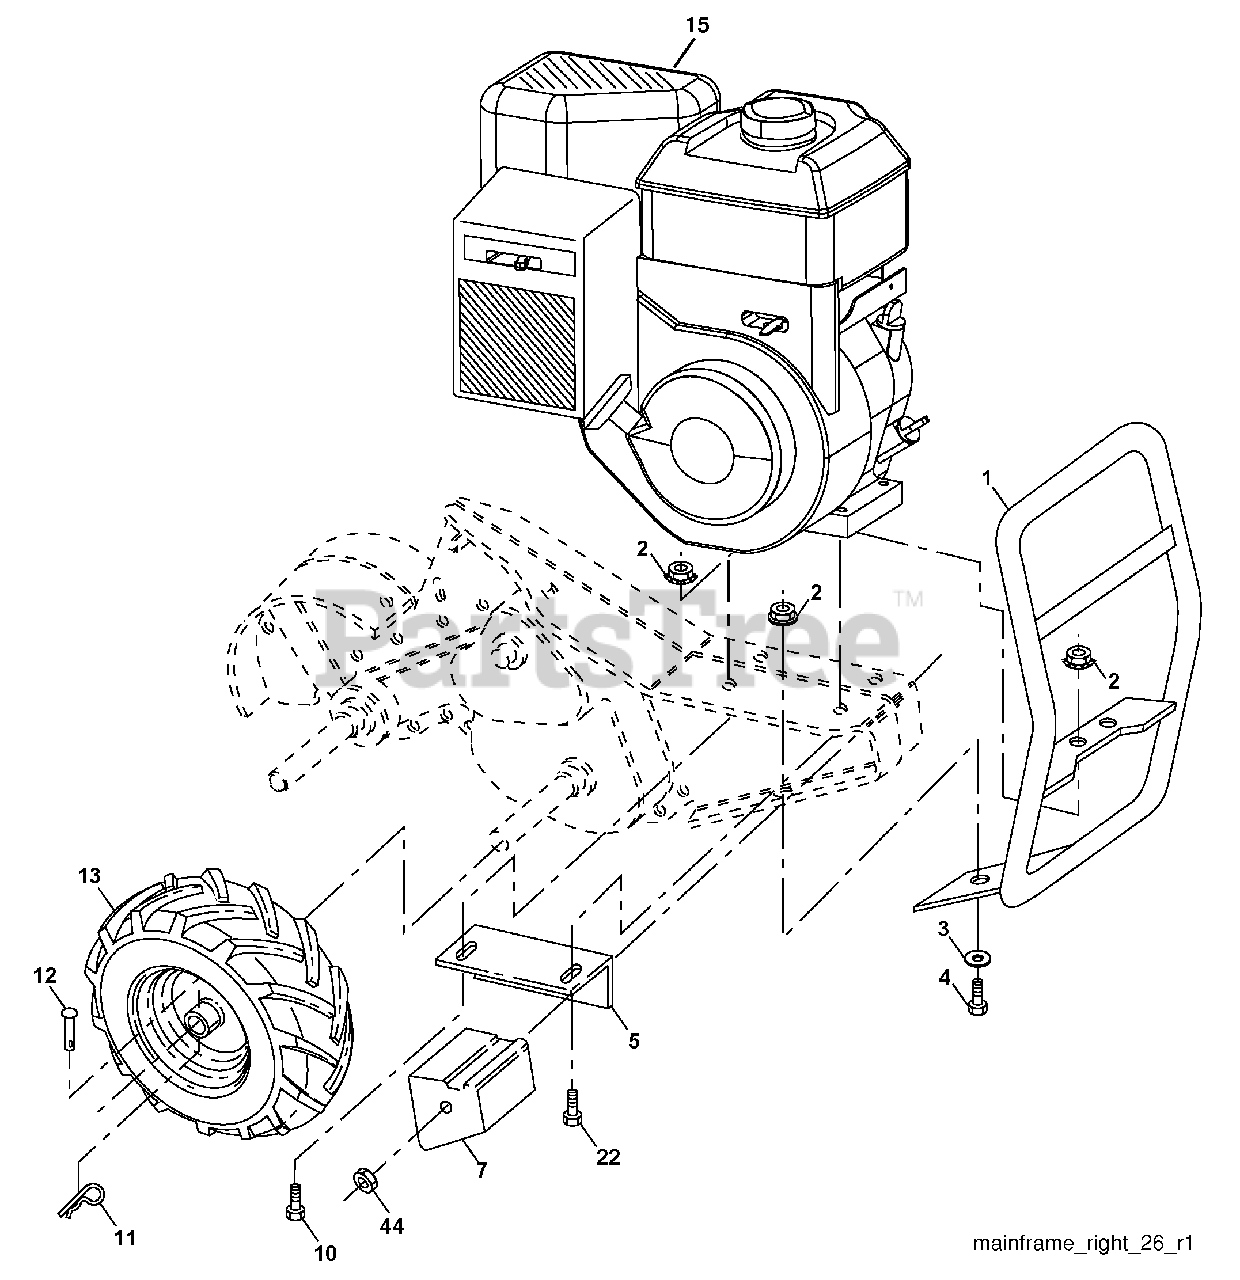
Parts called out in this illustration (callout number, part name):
2	Locknut, Hex, Flange 5/16-18
3	Washer 11/32 x 11/16 x 16 Ga.
4	Bolt, Hex 5/16-18 x 3/4
5	Bracket, Reinforcement
7	Counter Weight, R.H.
10	Bolt, Hex 5/16-18 x 1-1/2
11	Clip, Hairpin
12	Rivet, Drilled
13	Tire
13	Rim
13	Tire Valve
22	Bolt, Hex 5/16-18 x 1-3/4
44	Nut, Keps, Hex 3/8-16 unc
